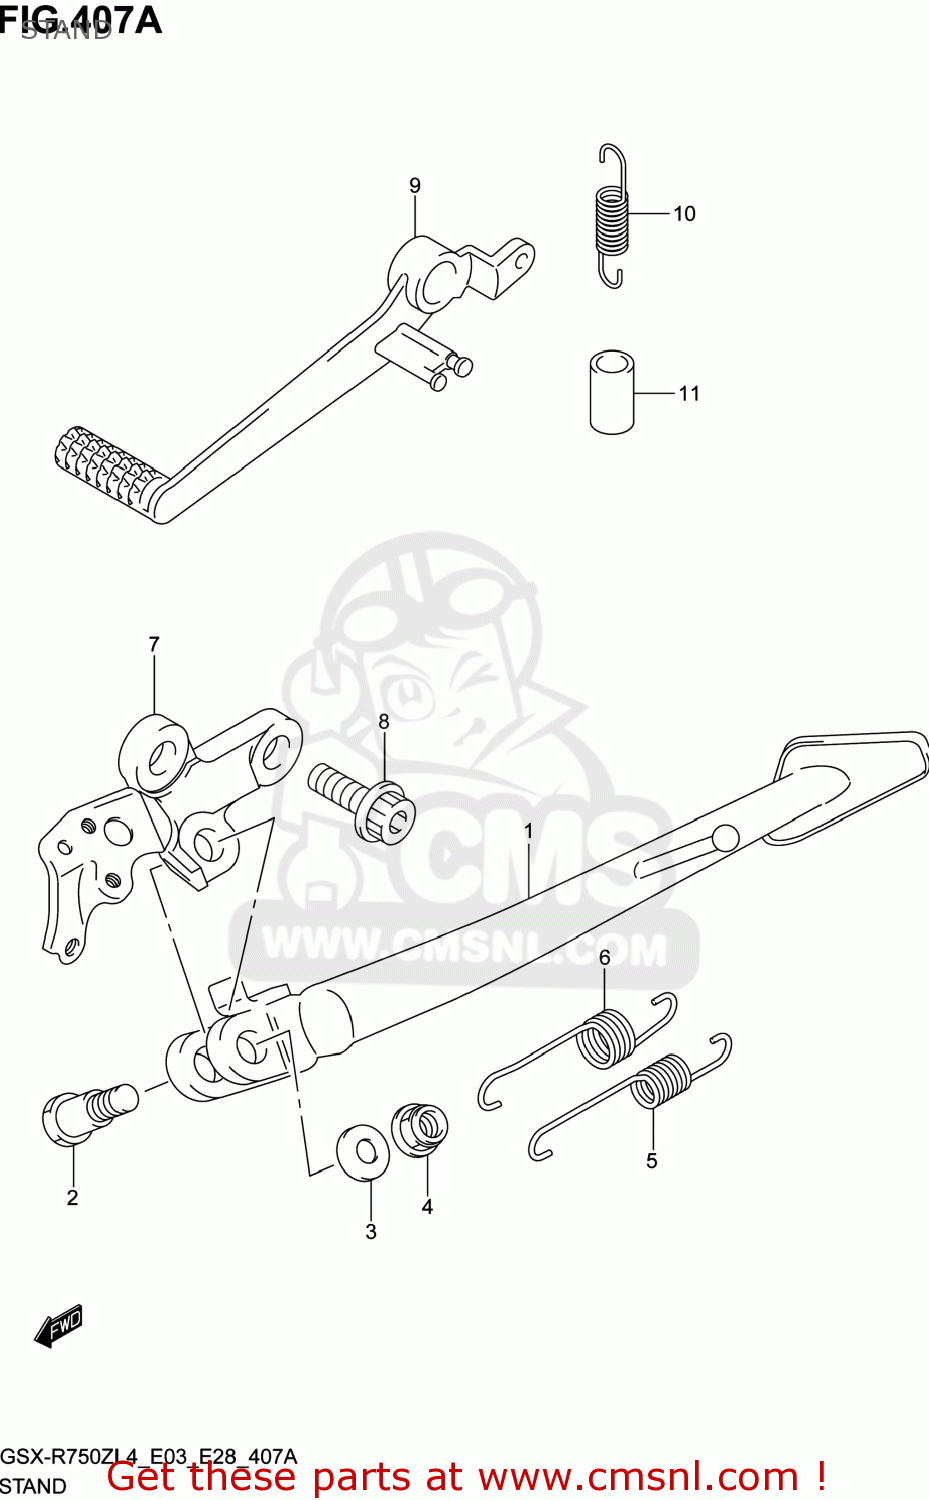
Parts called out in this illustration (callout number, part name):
1	STAND,PROP
2	BOLT,PROP STAND
3	SHIM(16X28X0.5)
4	NUT
5	SPRING
6	SPRING
7	BRACKET,PROP STAND
8	BOLT(10X28)
9	PEDAL,BRAKE
10	SPRING
11	HOSE(11X15X600)
